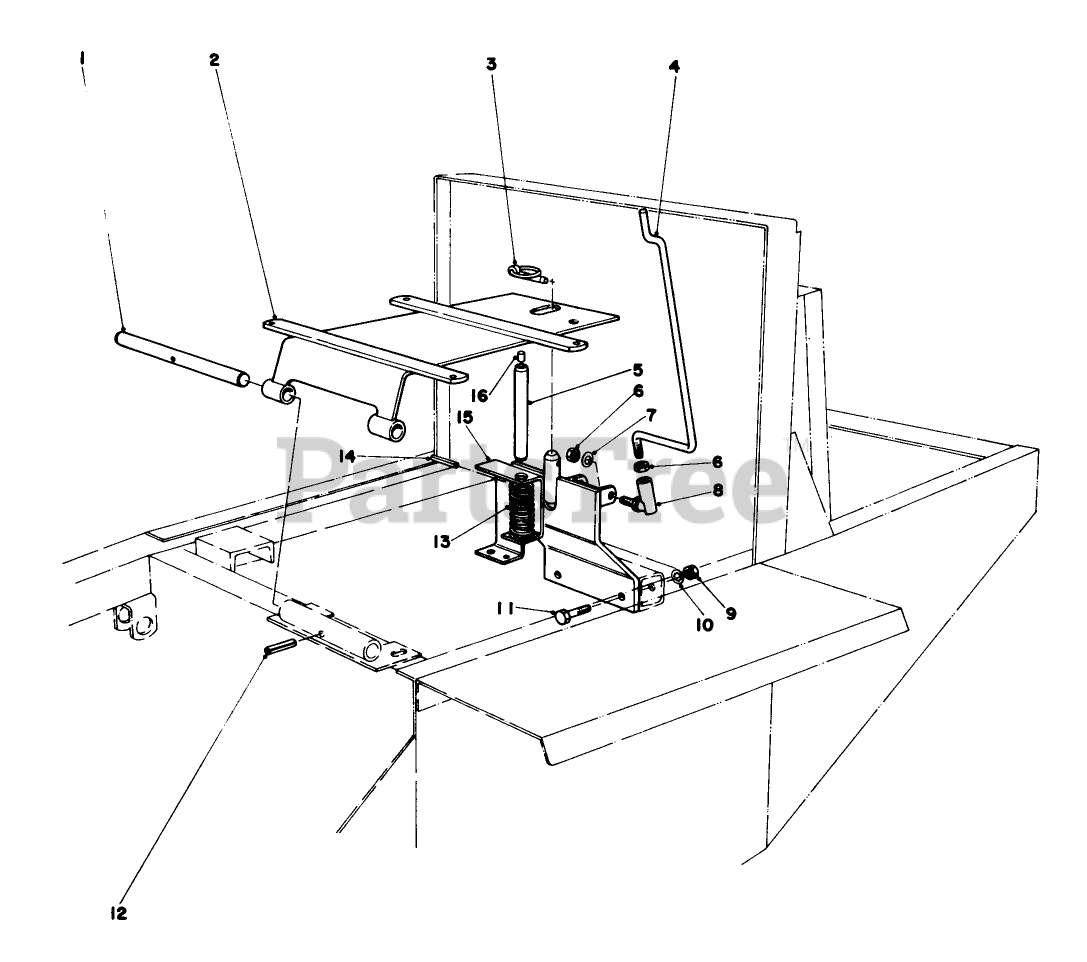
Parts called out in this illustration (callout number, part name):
1	SHAFT-PIVOT, SEAT
2	SEAT SUPT WA R
3	PIN-LYNCH
4	PROP SEAT
5	PIN-SWITCH, SEAT
6	NUT-JAM
7	WASHER-LOCK/SP
8	Ball Joint
9	NUT-HEX
10	WASHER-LOCK
11	SCREW-HH
12	PIN-ROLL, SLOTTED
13	SPRING-COMPRESSION
14	PIN-ROLL, SLOTTED
15	Bracket-Seat Support
16	PIN-PEDAL
